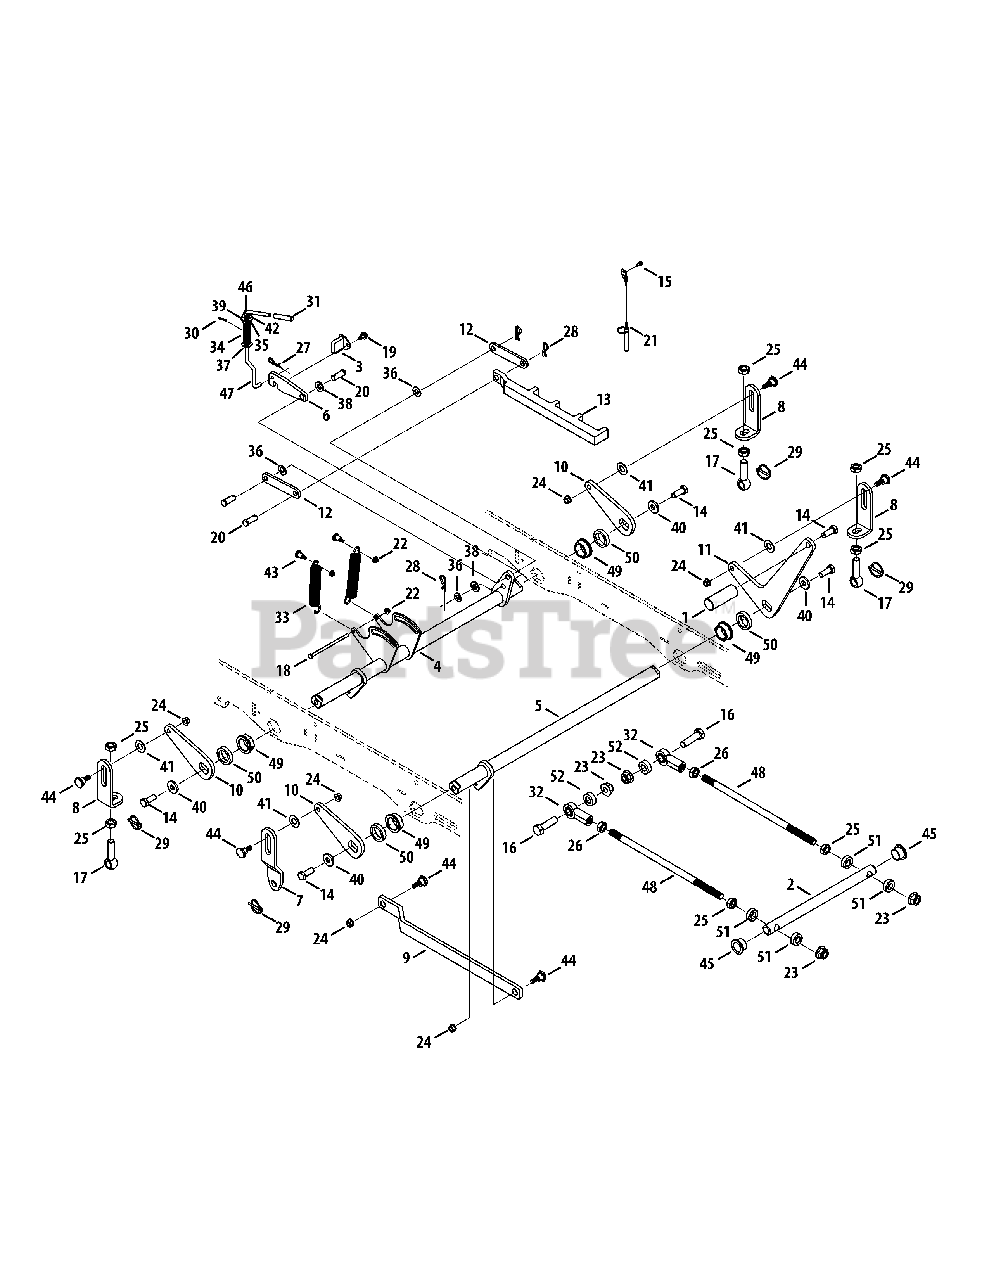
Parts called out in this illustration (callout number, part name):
1	Deck Lift Foot Pedal
2	Trail link Pivot Rod
3	Lift Lock Mount
4	Deck Lift Shaft
5	Deck Lift Shaft, Front
6	Latch Lock Bracket
7	Lift Link Arm
8	Deck Adjustment Lift Link Arm
9	Deck Lift Bar, Front
10	Deck Lift Bellcrank
11	Deck Lift Foot Pedal
12	Deck Index Link Arm
13	Lift Index Slider Arm
14	Hex Cap Screw, 1/2-13 x 1.25
15	Screw, #10-24 x .500
16	Hex Cap Screw, 5/8-11 x 2.25
17	Eye Bolt, 5/8-18 x 2.63
18	Hex Cap Screw, 1/4-20 x 5.00
19	Screw, 5/16-18 x .500
20	Clevis Pin, .500 x 1.25
21	Clevis Pin, .438 x 1.5
22	Nut, 1/4-20, Flangelock
23	Nut, 5/8-11, Flangelock
24	Nut, 3/8-16, Flangelock
25	Jam Nut, 5/8-11
26	Jam Nut, 5/8-18
27	Click Pin, .092 x 1.64
28	Internal Cotter Pin
29	Lynch Pin, .1875
30	Cotter Pin, 3/32 x .750
31	Lift Handle Grip
32	Ball Joint, .625 ID x 5/8-18
33	Extension Spring, .969 OD x 6.180
34	Compression Spring, .656 OD x 2.445
35	Bevel Washer, .340 x .872 x .060
36	Washer, .510 x 1.00 x .125
37	Shoulder Bushing, .320 ID x .135
38	Washer, .510 x 1.00 x .125
39	Washer, .640 x 1.20 x .125
40	Washer, .531 x 1.25 x .181
41	Washer, .640 x 1.25 x .050
42	Washer, .531 x .875 x .060
43	Shoulder Screw, .437 x .50, 1/4-20
44	Shoulder Screw, .625 x .442, 3/8-16
45	Bushing, 1.00 x 1.50 x .750
46	Bearing, .385 ID
47	Lift Lock Rod
48	Deck Rod, .625 Dia.
49	Hex Flange Bearing
50	Spacer, 1.27 x 1.75 x .375
51	Spacer, .635 x 1.188 x .406
52	Spacer, .635 x 1.25 x .445
